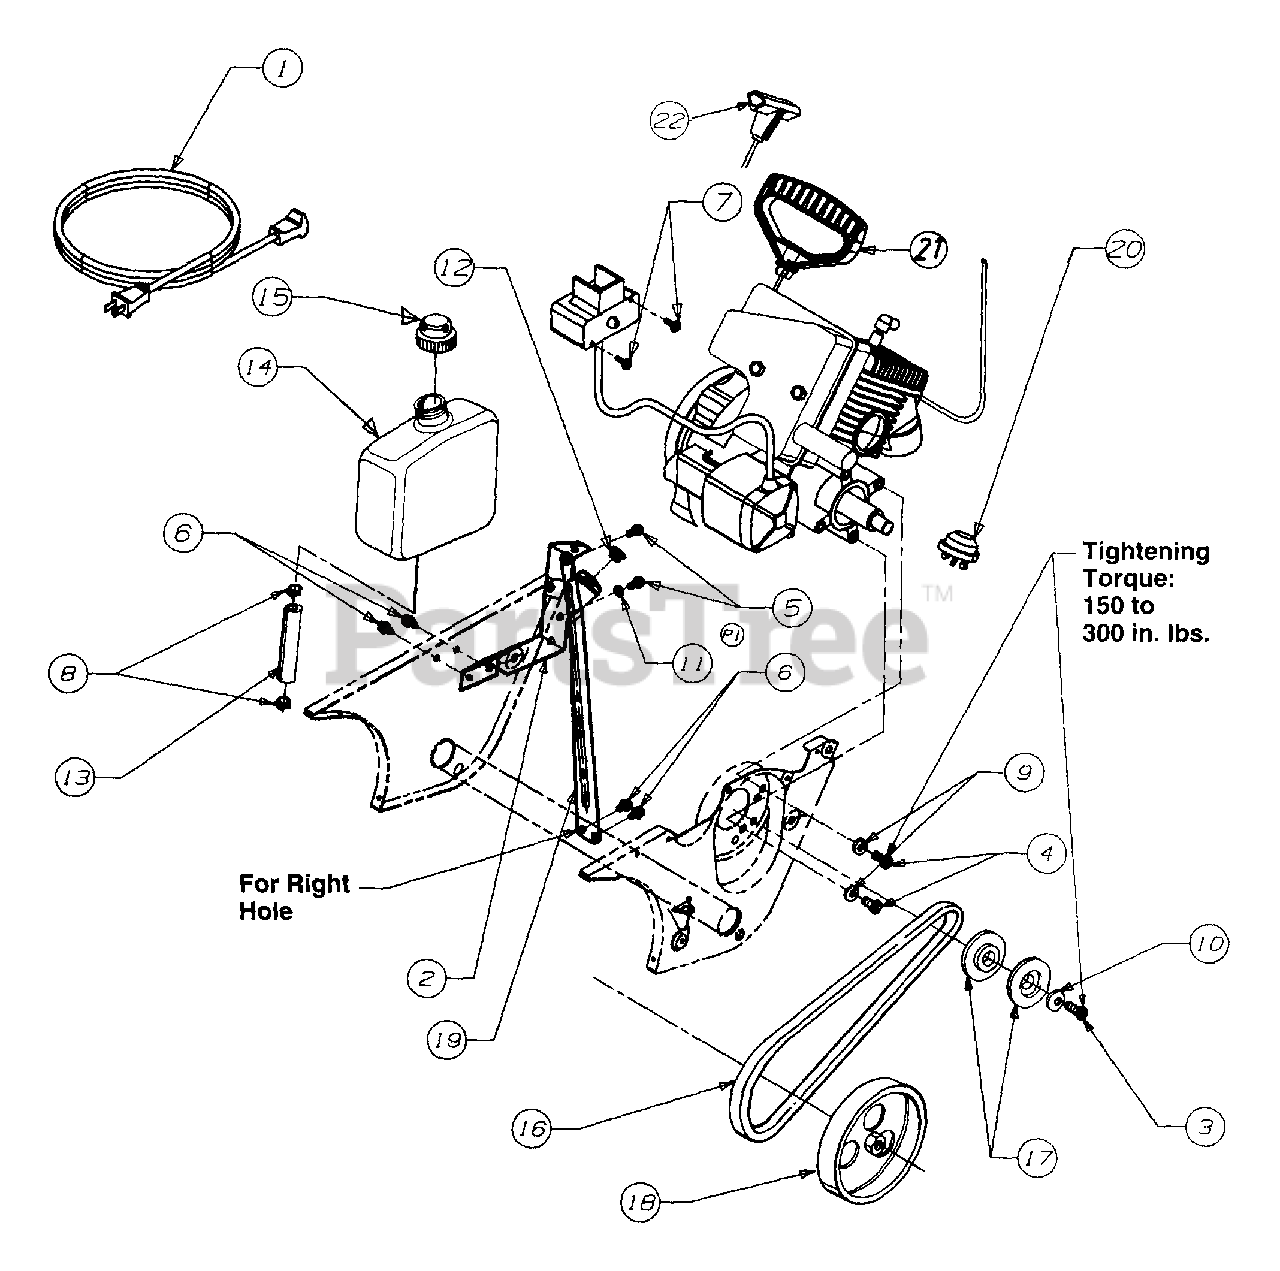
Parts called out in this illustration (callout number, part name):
1	Cord, Ext. 120V (E162 Only)
2	Gas Tank Support Brkt.
3	Scr., Hex Cap 5/16-24, .750 Gr. 5
4	Scr., Hex Cap 5/16-24, .620 Gr. 5
5	Scr., Hex Wash. 1/4-20, .500 Gr. 2
6	Scr., Hex Wash. 1/4 x .62 AB Tapp
7	Scr., Hex B-Tapp Wash. #10-16 x .62 (E162 Only)
8	Hose Clamp
9	L-Wash. 5/16 I.D.
10	Wash., Bell. .345 I.D. x .88 O.D. x .06
11	Wash., Lock 1/4
12	Bushing, Plastic
13	Hose, Fuel Line 25 x 16"
14	Tank, 2 Quart
15	Fuel Cap
16	V - Belt
17	V - Pulley Half
18	Pulley
21	Handle, Mitten (E162)
22	Handle, Recoil (152)
